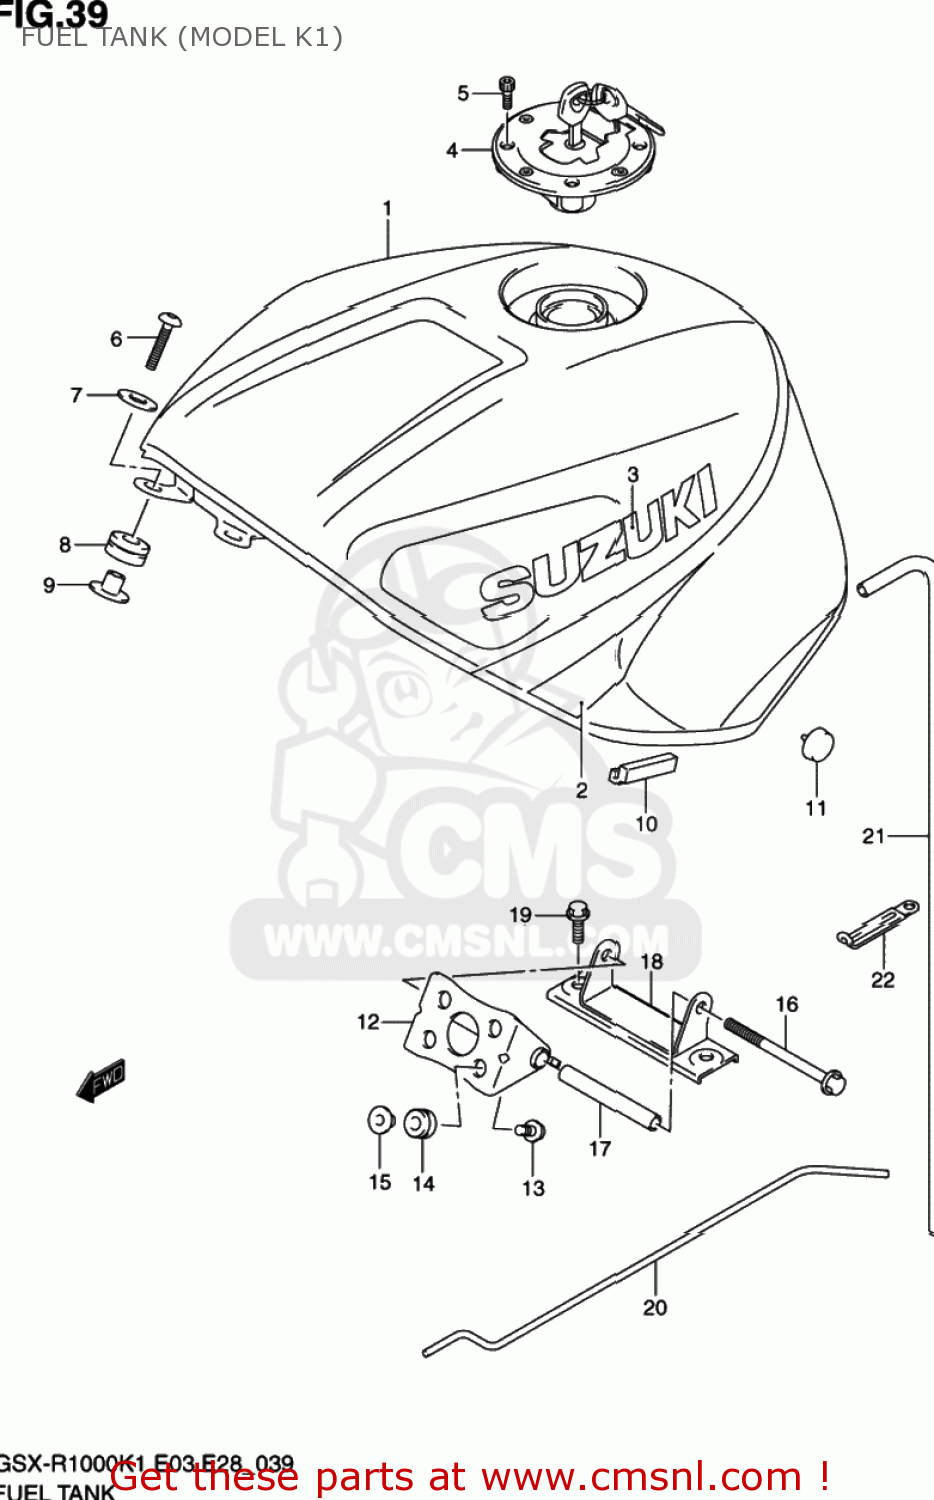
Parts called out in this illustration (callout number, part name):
1	TANK ASSY,FUEL
2	TAPE SET,FUEL TANK
3	EMBLEM,FUEL TANK
4	CAP SET,FUEL TANK
5	BOLT(5X20)
6	SCREW(6X25)
7	WASHER(6.5X22X1.6)
8	CUSHION,FUEL TANK FR
9	SPACER,FUEL TANK FR
10	CUSHION,FUEL TANK SIDE
11	CUSHION,FUEL TANK SIDE NO.2
12	BRACKET,FUEL TANK NO.1
13	BOLT(6X20)
14	CUSHION
15	WASHER
16	BOLT
17	SPACER,FUEL TANK RR
18	BRACKET,FUEL TANK NO.2
19	BOLT
20	STAY,FUEL TANK
21	HOSE,FUEL TANK WATER DRAIN
22	CLAMP(L:65)
